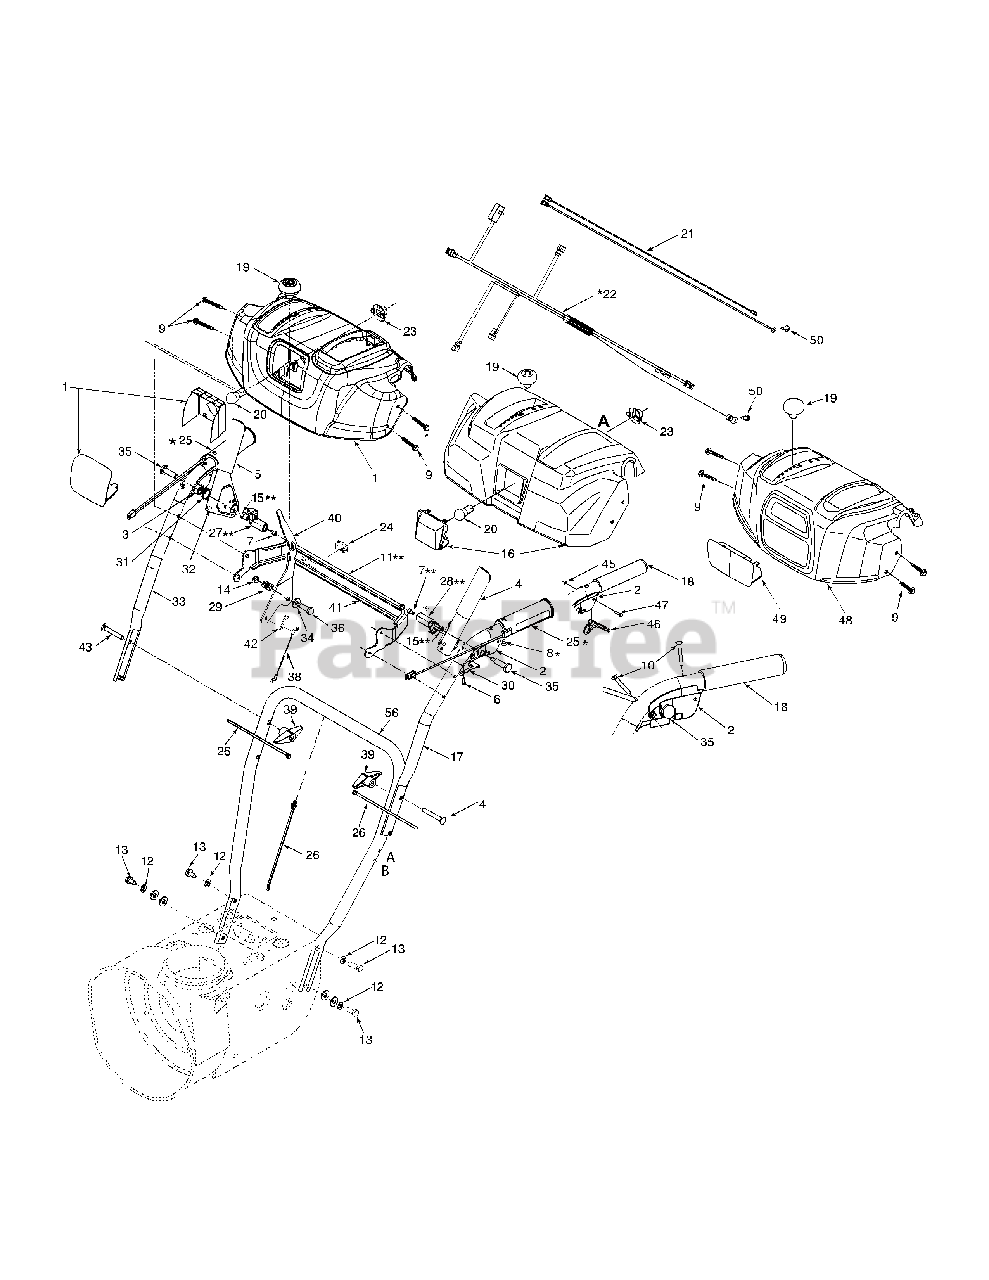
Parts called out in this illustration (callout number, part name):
1	Handle Panel Ass’y-Black w/Chute control
2	LH Clutch Lock Handle Ass’y
3	RH Clutch Lock Handle Ass’y
4	Engagement Handle Assembly LH - Black
5	Engagement Handle Assembly RH - Black
6	Screw #8-16 x .50
7	Hex Cap Socket Screw 1/4-20 x .5
8	Oval HD C-Sunk Scr #10 x 5/8
9	Hex TT-Tap Scr 1/4-20 x 1.625
10	Oval C-Sunk Hd Screw 10-24 x 1.375
12	Lockwasher 5/16 ID
13	Hex TT Screw 5/16-18 x .75 Gr. 5 Patch
14	Hex L-Flanged Nut 1/4-20 Gr. F Nylon
15	Hex Shoulder Nut 1/4-20
16	Handle Panel Ass’y
20	Lamp
22	Heated Grip Wire Harness
23	Socket
26	Cable Tie (w/plug)
28	Clutch Lock Cam
29	Compression Spring .38 ID x .88 Lg
30	Spring: Clutch Lock
31	Torsion Spring .8156 x .3038
32	Rubber Bumper
34	Flat Washer .38 ID x .87 OD x .09
35	Shoulder Screw .437 x 1.345: 1/4-20
36	Shoulder Screw .374 Dia. x 1.05 Lg.
37	Flat Washer .344 ID x .688 OD x .065
38	Selector Speed Cable
39	Handle Knob Assembly
41	Panel Support
42	Cotter Pin
43	Carriage Bolt 5/16-18 x 2.25
44	Lower Handle
46	Steering control - Black
48	Handle Panel Ass’y - Red (w/lens)
49	Lens
50	Hex Wash S-Tapp Scr 1/4-20 x .50
